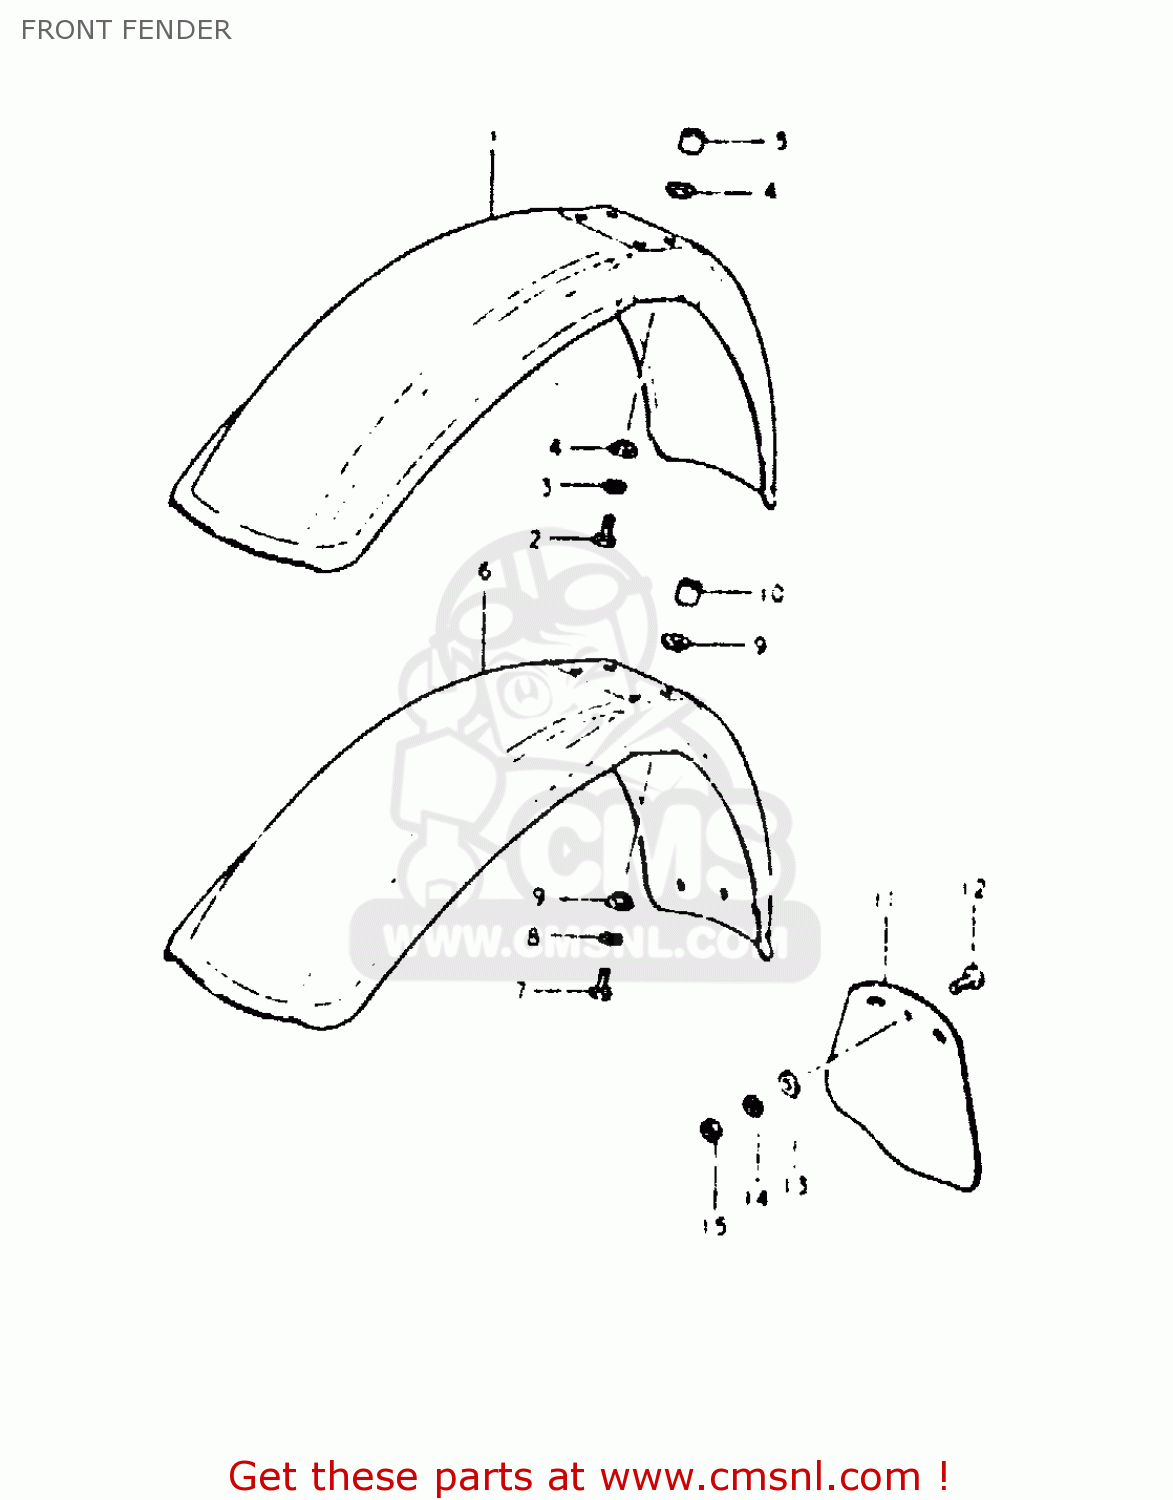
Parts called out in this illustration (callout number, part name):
1	FENDER,FRONT
2	BOLT
3	LOCK WASHER
4	WASHER
5	SPACER (6.8X10X27.4)
